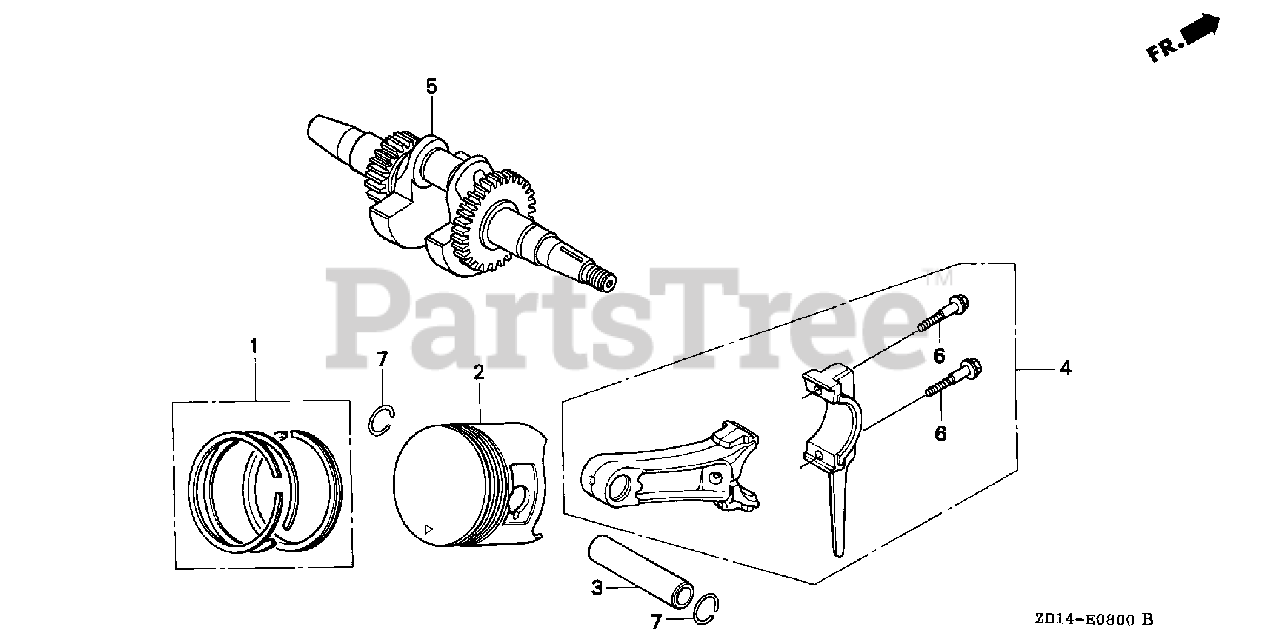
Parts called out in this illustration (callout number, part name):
1	RING SET, PISTON (STD) (NIPPON)
1	RING SET, PISTON (STD) (TEIKOKU)
1	RING SET, PISTON (OVER SIZE) Use up to Engine SN 1817922.
1	RING SET, PISTON (OVER SIZE)
2	PISTON (STD)
2	PISTON (OVER SIZE) (0.25)
2	PISTON (OVER SIZE) (0.50)
2	PISTON (OVER SIZE) (0.75)
3	PIN, PISTON
4	ROD ASSY., CONNECTING
5	CRANKSHAFT
6	BOLT, CONNECTING ROD
7	CLIP, PISTON PIN (13MM)
